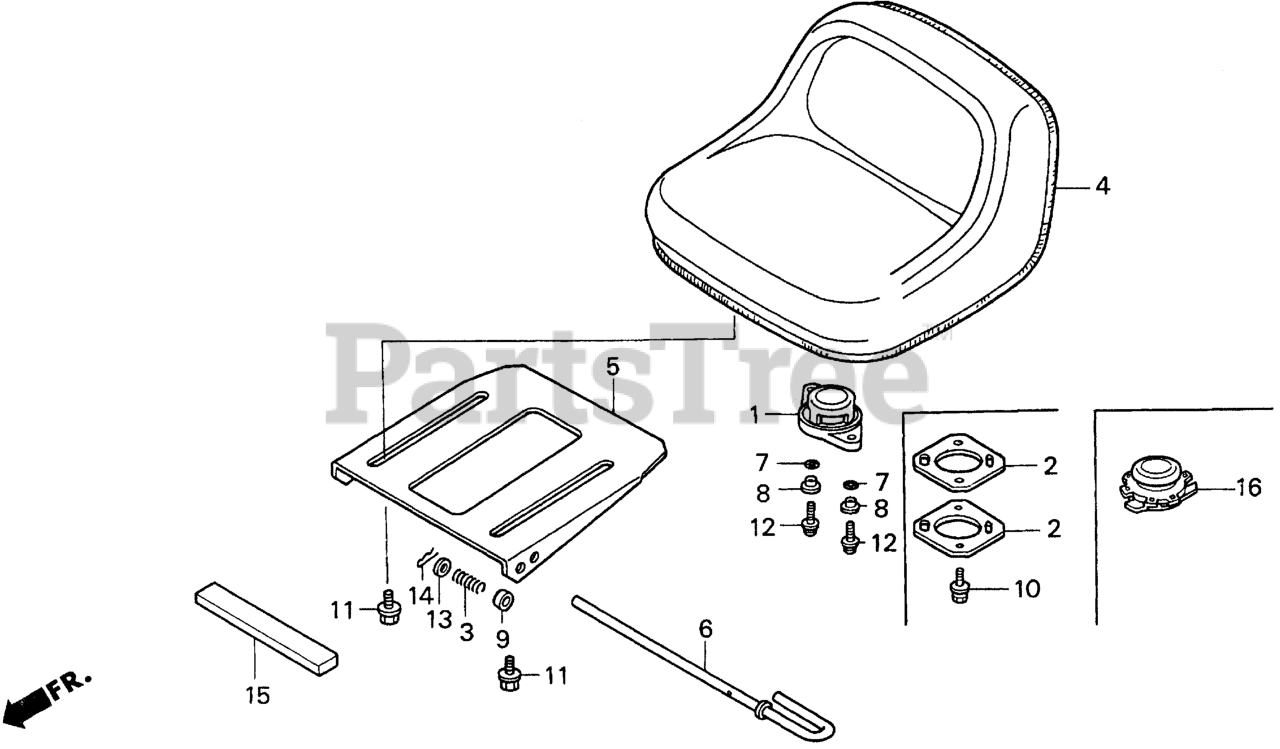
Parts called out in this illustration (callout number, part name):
1	SWITCH ASSY., SEAT
3	SPRING, MAINTENANCE COVER
4	SEAT ASSY.
5	BASE, SEAT
6	PIN, SEAT HINGE
7	O-RING (7.8X1.9) (NOK)
8	COLLAR, SEAT SWITCH
11	BOLT-WASHER (8X16)
12	SCREW-WASHER (5X16) Use up to Engine SN 2056819.
13	WASHER, PLAIN (8MM)
14	PIN, LOCK (8MM)
